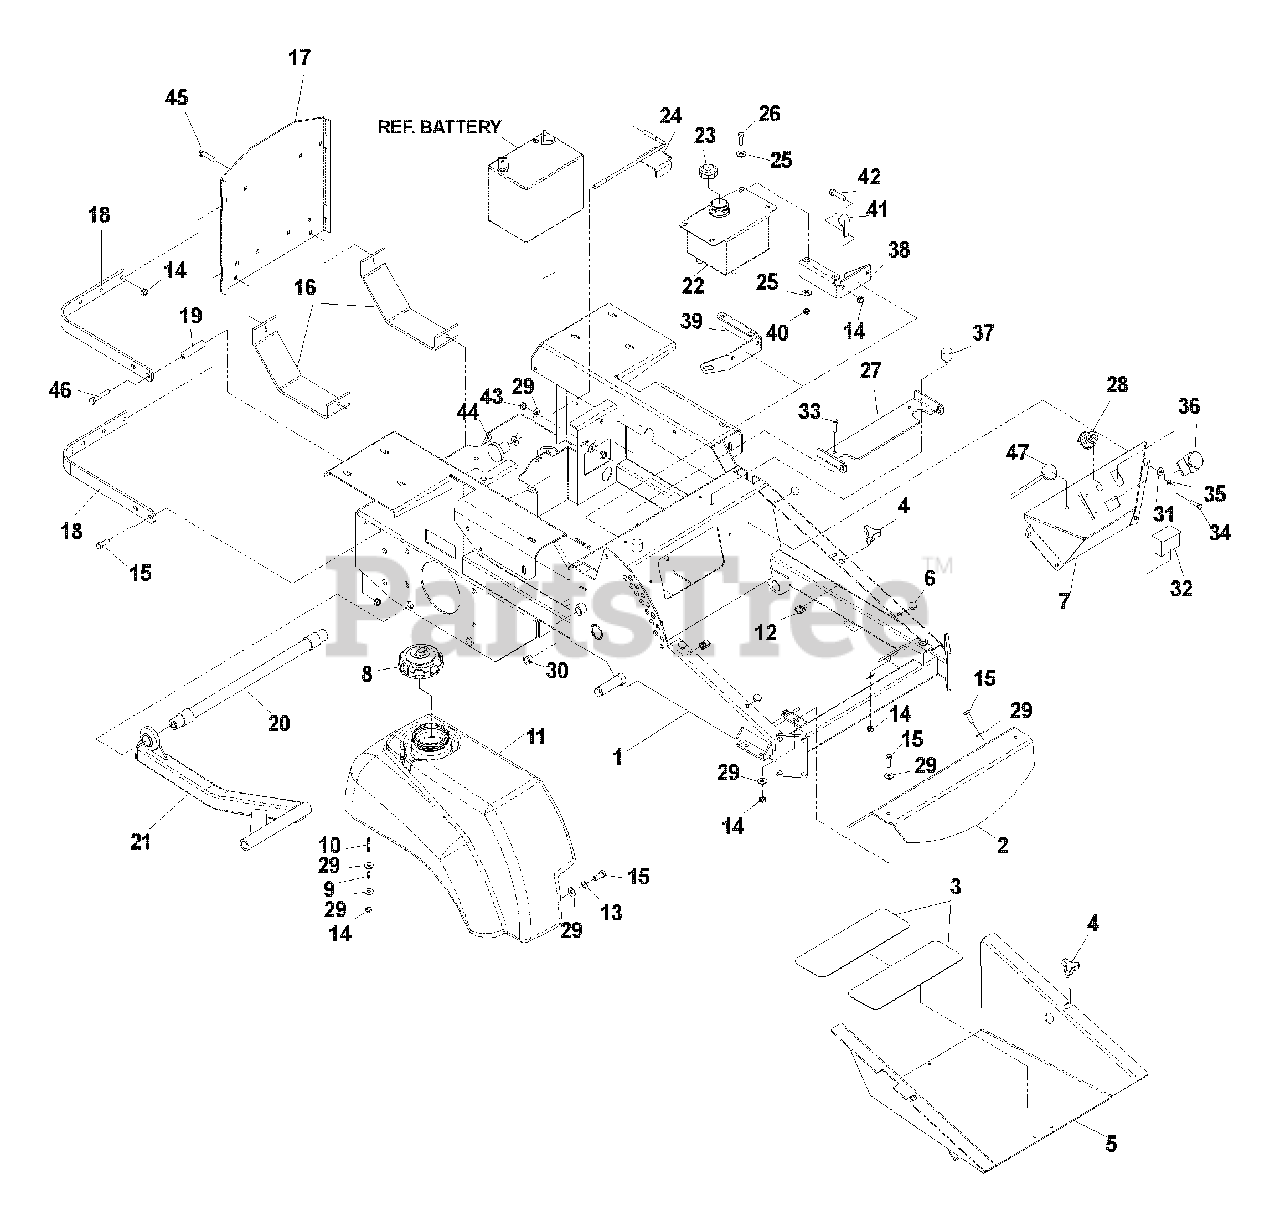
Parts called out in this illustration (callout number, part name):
1	FRAME W/DECALS
3	ANTI-SKID PAD
4	KNOB W/STUD
5	FOOT PLATE
7	CONSOLE WLDMT.
8	FUEL CAP
11	FUEL TANK, RIGHT
12	"U" CLIP, 5/16C
13	LOCKWASHER, 5/16
14	NUT, 5/16C, NYLOC
15	HCS 5/16C X 1
16	SKID PLATE
17	ENGINE GUARD
20	STRUT MT WLDMT
21	STRUT, RIGHT
23	CAP OIL TANK
24	BATTERY HOLD DOWN
25	WASHER, 1/4, FLAT
26	HCS 1/4C X 3/4
27	SEAT BKT W/DECAL
28	SWITCH, IGNITION
29	WASHER, 5/16, FLAT
31	WASHER, 1/4, FLAT
32	HOUR METER
33	HCS 1/4C X 3/4
34	TFS 1/4C X 5/8
35	LOCKWASHER, 1/4
36	BLADE SWITCH
37	STUD/PLATE MOUNT
38	TANK MOUNT, RIGHT
39	TANK MOUNT, LEFT
40	NUT, 1/4C, NYLOC
42	HCS 5/16C X 3/4
43	LOCKNUT, 5/16C
45	RHSSNB 5/16 X 1
46	HCS 5/16C X 4
47	CHOKE CONTROL
